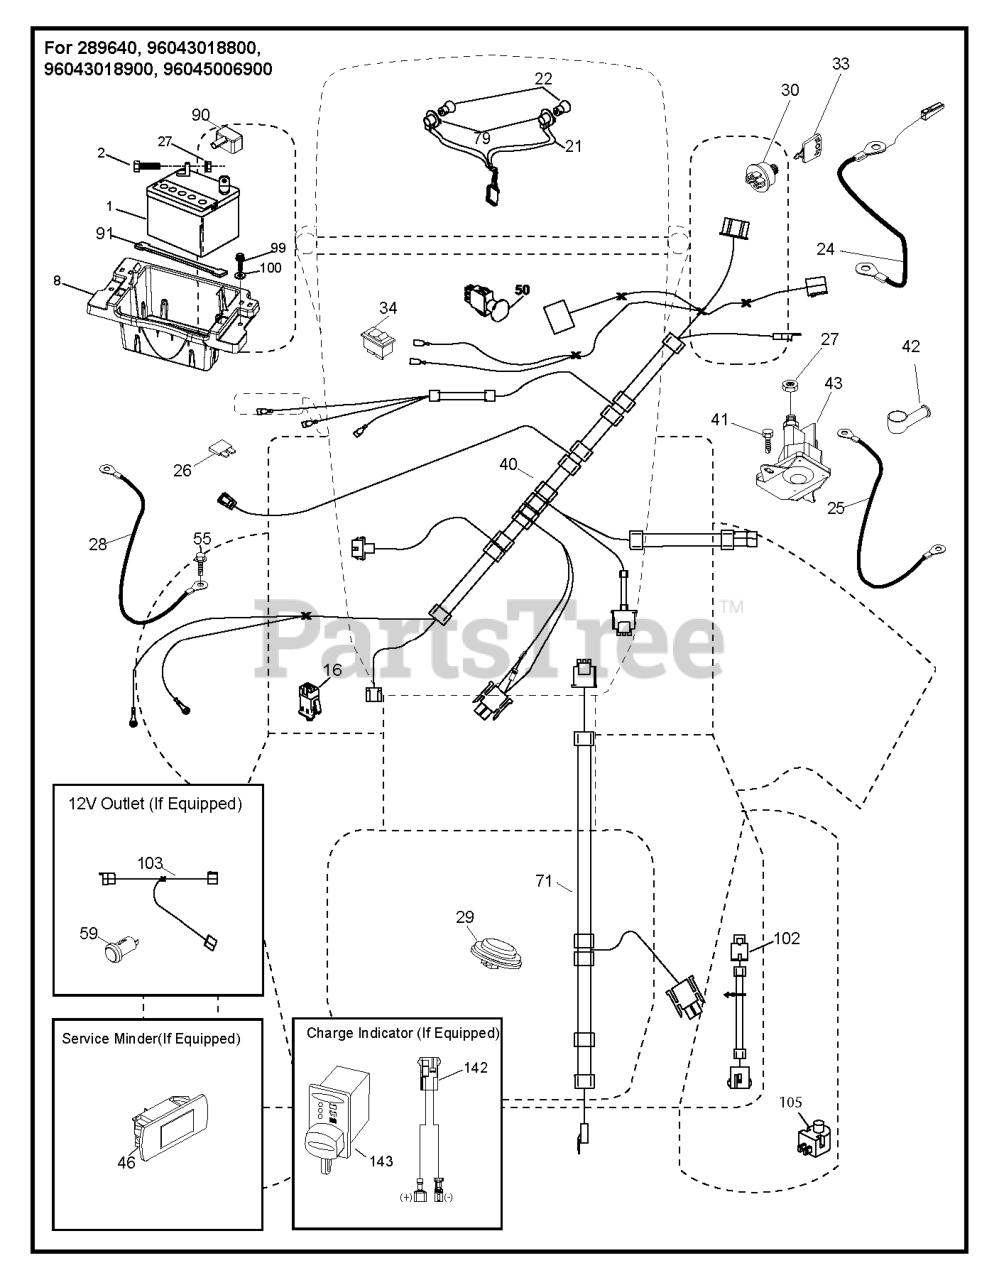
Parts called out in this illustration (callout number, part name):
1	Battery 12 Volt 25 Amp
2	BOLT.HEX.1/4.X.3/4.DICHROMATE
8	BOX.BATTERY.MOUNT.FRONT.LT
8	TRAY.ASM.BATTERY.FRT.TEX.CARB
8	TRAY.BATTERY BOX.FRONT
16	SWITCH INTERLOOK PUSH-IN
21	HARNESS ASSY LIGHT
21	HARNESS.LIGHT W/4152J BULBS
24	CABLE.FRBATT.W/WIRE.8GA.8
25	CABLE.STARTER.8GA.17.5
26	FUSE 20AMP
27	NUT HEX_LRG FLG_1_4-20_LOCK
28	CABLE GROUND 6 GA 21" 90T BLK
28	CABLE.GROUND.21"BLK.8GA.90T
29	SWITCH.SEAT.DELTA.OPC.
30	SWITCH.IGN.DELTA.W.LGH.ROS
33	KEY.CHAIN.BLISTER.PACK.GEN.INT
33	KEY.CHAIN.BLISTER.PACK.GEN.USA
40	HARNESS.IGN.DASH.HUQ/P
40	HARNESS.TEX.DASH.ELEC.REAR BAT
40	HARNESS HARNESS..DASH.ING.ELEC
41	SCREW
42	TERMINAL COVER
46	GUAGE.SRVCMNDR.HRMTR.
46	RP.GUAGE.SRVCMNDR.HRMTR.
50	RP SWITCH.PTO.TERMINAL.STD.RED
55	SCREW 5/16"
71	HARNESS-CHASSIS SUB
71	HARNESS.CHASSIS.RRBATT.RDYSTRT
79	BULB HOLDER ASM.
90	COVER.TERMINAL.BATTERY
91	STRAP.BATTERY.MOUNT.FRONT(2 2)
99	SCREW HEXWSHR 1/4-20X3/4
102	HARNESS PIGTAIL PCH TEX ROS
105	REVERSE SWITCH
